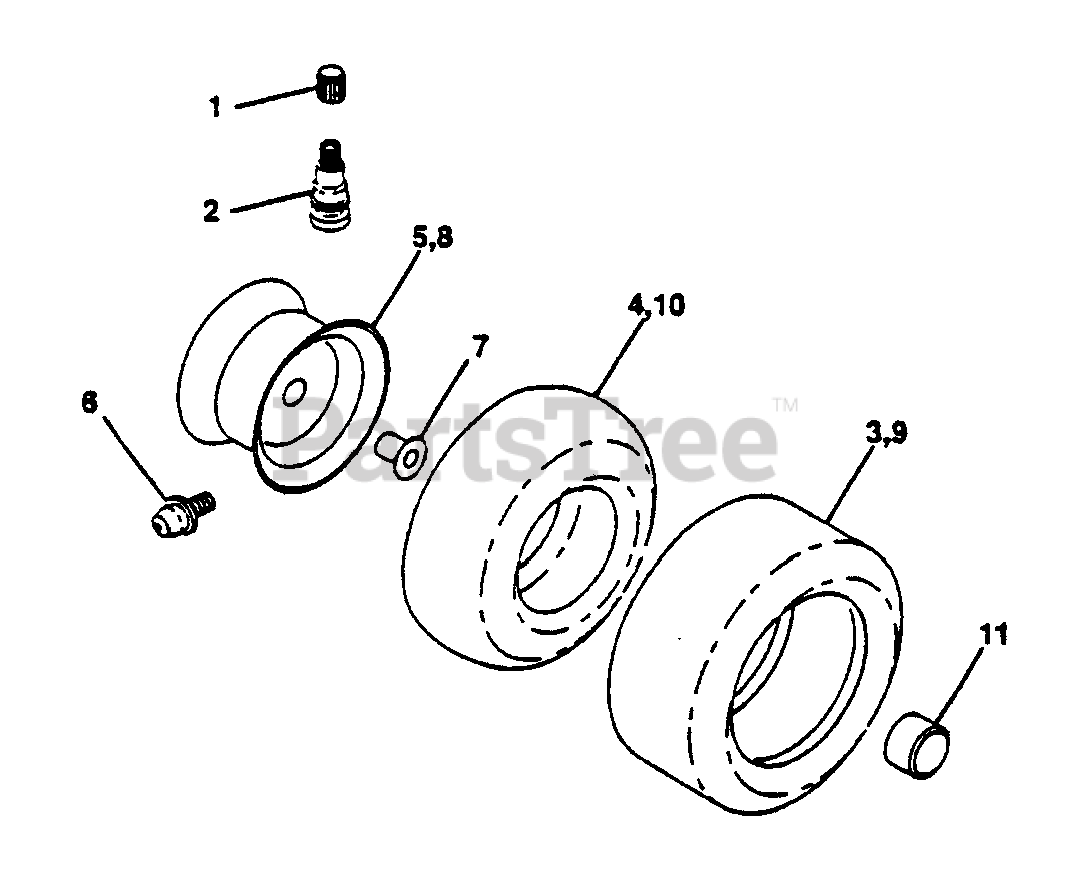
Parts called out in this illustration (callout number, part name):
1	Cap Valve Tire
2	Stem Valve
3	Tire F Ts 15 X 6 0 - 6 Service
4	Tube Front
5	Rim Asm 6" front White Service
6	Fitting Grease
7	Bearing Flange
8	Rim Asm 8" rear White Service
9	Tire R Ts 18x8 5-8 C Service
10	Tube Rear
11	Cap Axle Blk 1 50 X 1 00
